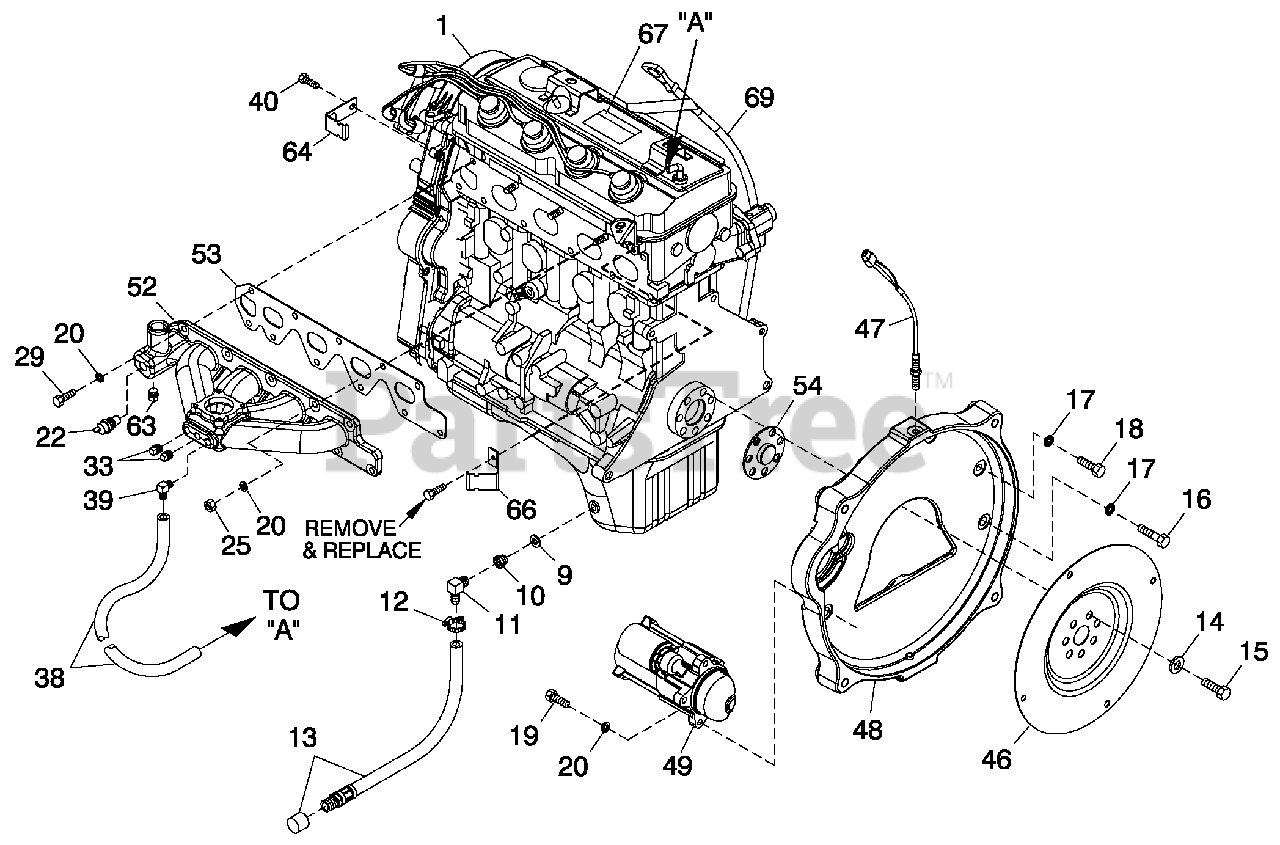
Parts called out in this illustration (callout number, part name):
1	ENGINE 2.4LG 24G 64 CERT
2	WASHER LOCK M10
3	SCREW HHC M8-1.25 X 35 G8.8
4	SCREW SHC M14-1.5 X 35 G10.9
5	ALTERNATOR DC W/OUT PULLEY
6	SPACER DC ALTERNATOR PULLEY
7	ADAPTOR 1/8 NPTFTO 1/8 BSPT
8	SWITCH OIL PRESSURE 10 PSI 2 POL (R-PANEL)
9	WASHERNYLON 565
10	ADAPTER M14-1.50X 3/8 NPT
11	BARBEDEL 90 3 /8N PT X 3/8
12	CLAMP HOSE.38-.87
13	HOSE DRAIN ASSY 28"
14	WASHERFLAT .531 ID X 1.062 OD
15	SCREW HHC M12-1.25 X 20 G10.9
16	SCREW HHC M10-1.25 X 45 G8.8
17	WASHER SHAKEPROOF EXT 7/16 STL
18	SCREW HHC M10-1.25 X 30 G8.8
19	SCREW SHC M8-1.25 X 30 G 12.9
20	WASHER LOCK M8-5/16
21	SCREW THF M6 -1 X 16 NWAZ/JS
22	SWITCH HI-TEMP 245D X 3/8 NPT (R-PANEL)
23	WASHER FLAT 5/16-M8 ZINC
25	NUT HEXM8-1.25 G8 CLEAR ZINC
26	WASHER FLAT 3/8-M10 ZINC
27	NUT HEX M6 X 1.0 G8 YEL CHR
28	NUT HEX M10-1.25 G8 YEL CHR
29	SCREW SHC M8-1.25 X 25G12.9
30	WASHER LOCK M6-1/4
31	WASHER FLAT 1/4-M6 ZINC
32	SCREW HHC M6-1.0 X 12 G8.8
33	PLUG STD PIPE 1/4 STEEL SQ HD
34	SCREW HHC M10-1.5 X 60G 8.8
35	SCREW HHC M8-1.25 X 25G 10.9
36	OIL FILTER G2 ENGINE
37	COIL PACK
38	HOSE 3/8 ID SINGLE BRAID (15" LG)
39	BARBED EL 9 0 1 /4 NPT X 3/8
40	SCREW HHC M6-1.0X 25 G8.8
44	GASKET EXHAUST MANIFOLD
45	EXHAUST MANIFOLD G2 (MACHINE) (25KW, 35KW & 45KW)
46	FLEX PLATE 2 POLE 2.4LG 2
47	ASSYMAGPICK UP(3/8-24MALE)
48	ADAPTER ENGINE 2.4L MACHNE
49	STARTER MOTOR 12V
50	CAM SENSORPIN ASSY
51	COVER CAM GEAR G2 REWORKED
52	MANIFOLD INTAKE (USE HOSE 0G0816)
53	GASKET INTAKE MANIFOLD
54	SPACER 2.4LG2 FLEX PLATE
55	SHELD HEAT G2
56	SHELD HEAT SML
57	BRACKET COIL PACK
59	ADAPTER 2.4L CRANKSHAFT MACH
60	POLYV-BELT G2 (3600 RPM)
61	PULLEY DC ALTERNATOR (3600 RPM)
62	SCREW HHC M6-1.0X 35 G8.8BLK
63	PLUG STD PIPE 3/8 STEEL SQ HD
64	BRACKET, SIGNAL CONDITIONER
65	SCREW HHC M8-1.25 X 70G 8.8
66	BRACKET SIGNAL CONDITONER
67	DECAL EMISSION CTRLINFO 2.4L
69	ROD ASSY OIL LEVEL GAUGE
70	O-RING SIZE 9.0MM X 20MMNITR
71	CABLE, SPARKPLUG, NO.1
72	CABLE, SPARKPLUG, NO.2
73	CABLE, SPARKPLUG, NO.3
74	CABLE, SPARKPLUG, NO.4
75	PLUG TAPER
